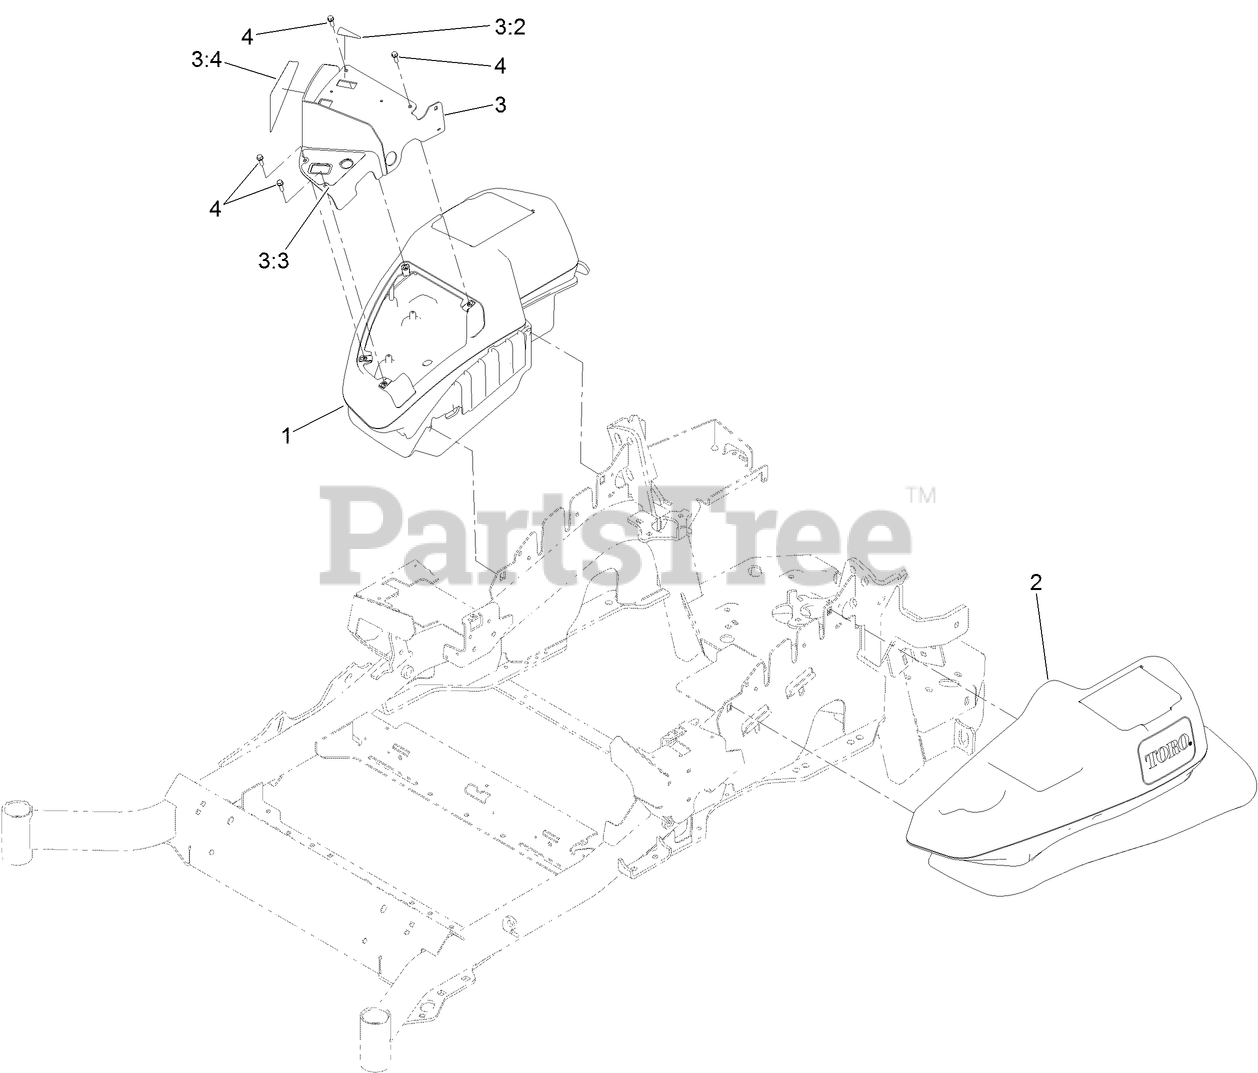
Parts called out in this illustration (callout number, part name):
1	RH CONSOLE ASM
2	LH CONSOLE ASM
3	CONTROL PANEL ASM
3:2	DECAL-CONSOLE
3:3	DECAL-CONTROL PANEL
3:4	DECAL-HORIZON
4	SCREW-HWH
